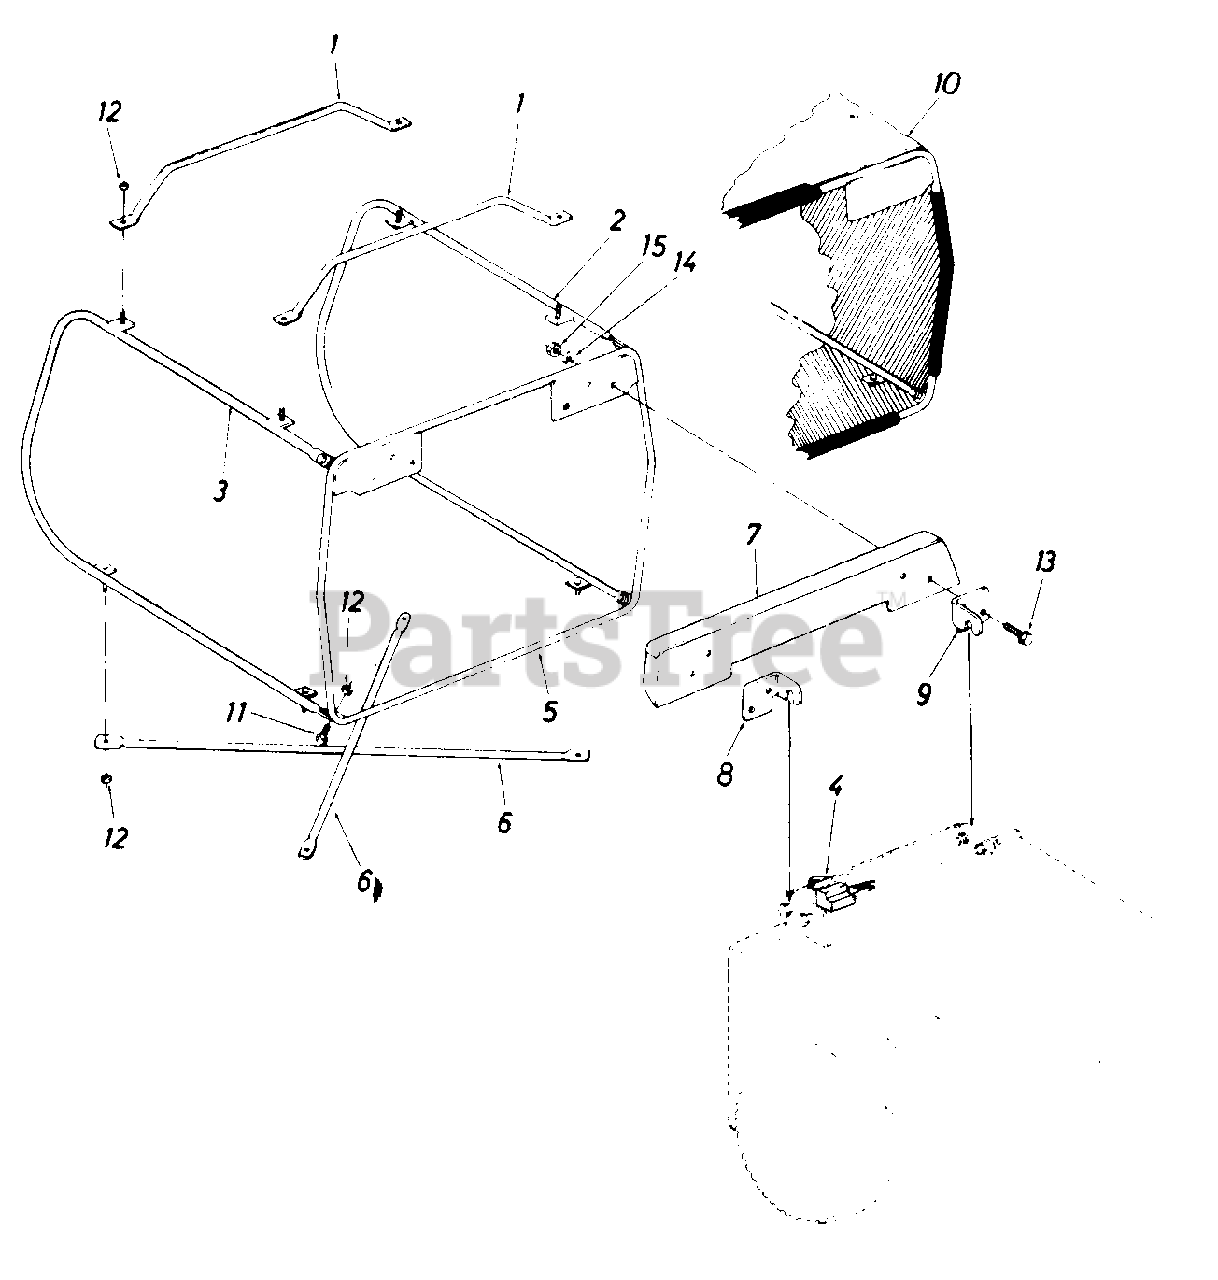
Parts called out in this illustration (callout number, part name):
1	Catcher Handles
2	Catcher Side Frame Ass'y. L.H.
3	Catcher Side Frame Ass'y. R.H.
4	Safety Switch
5	Catcher Frame Ass'y.
6	Bottom Cross Brace
7	C) ust Cover
8	Hinge-R.H.
9	Hinge-L.H.
10	Grass Bag
11	Hex Scr. 1/4-20 x .62" Lg.
12	Hex Cent. L-Nut 1/4-20 Thd.
13	Hex Sems Scr. 5/16-18 x 1.00" Lg.
14	L-Wash. 5/16" Scr.
15	Hex Nut 5/16-18 Thd
